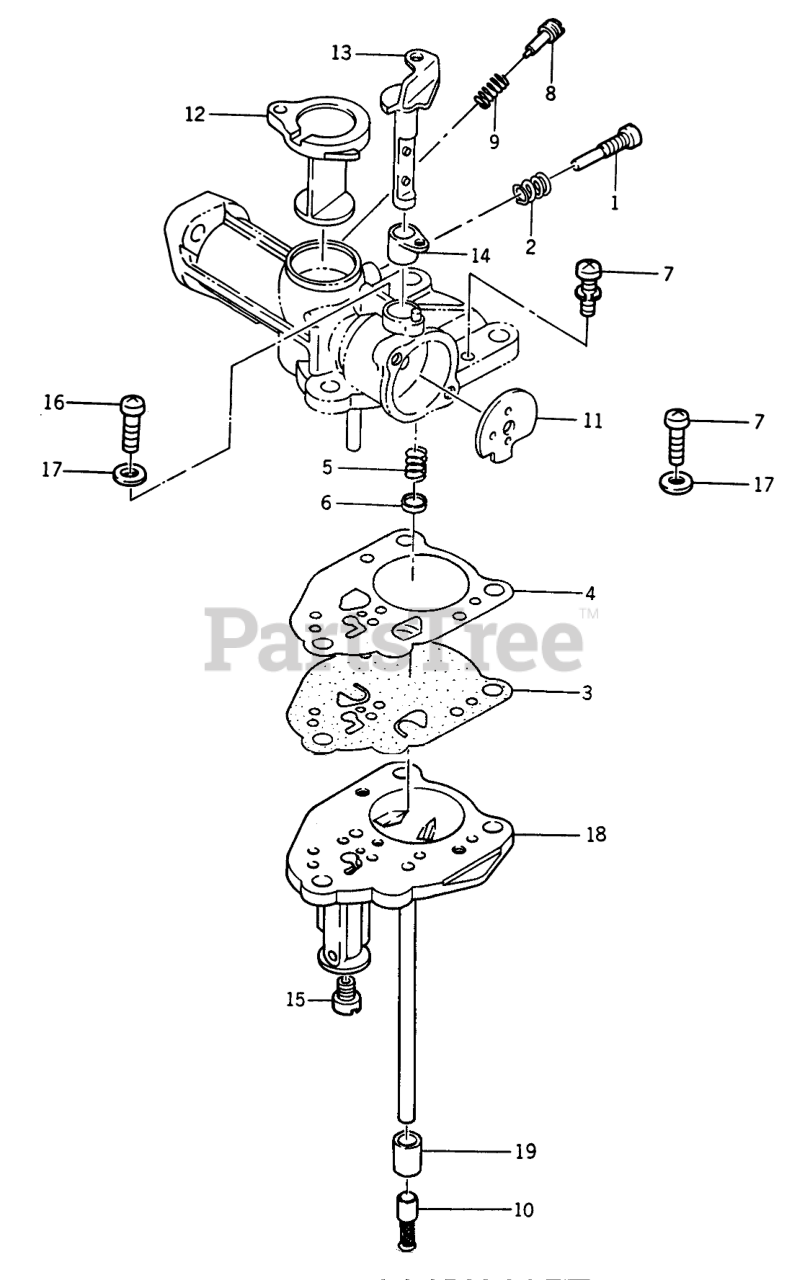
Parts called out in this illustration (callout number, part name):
1	SLOW STOP SCREW
2	SPRING
3	DIAPHRAGM
4	GASKET
5	SPRING
6	SPRING CAP
7	Screw 4 x 14
8	ADJUST SCREW
9	Spring
10	STRAINER
11	CHOKE VALVE
12	THROTTLE SHAFT
13	CHOKE SHAFT
14	COLLAR
15	MAIN JET (#72)
16	SCREW (4X28)
17	Gasket
18	LOWER BODY ASS'Y
19	COLLAR
